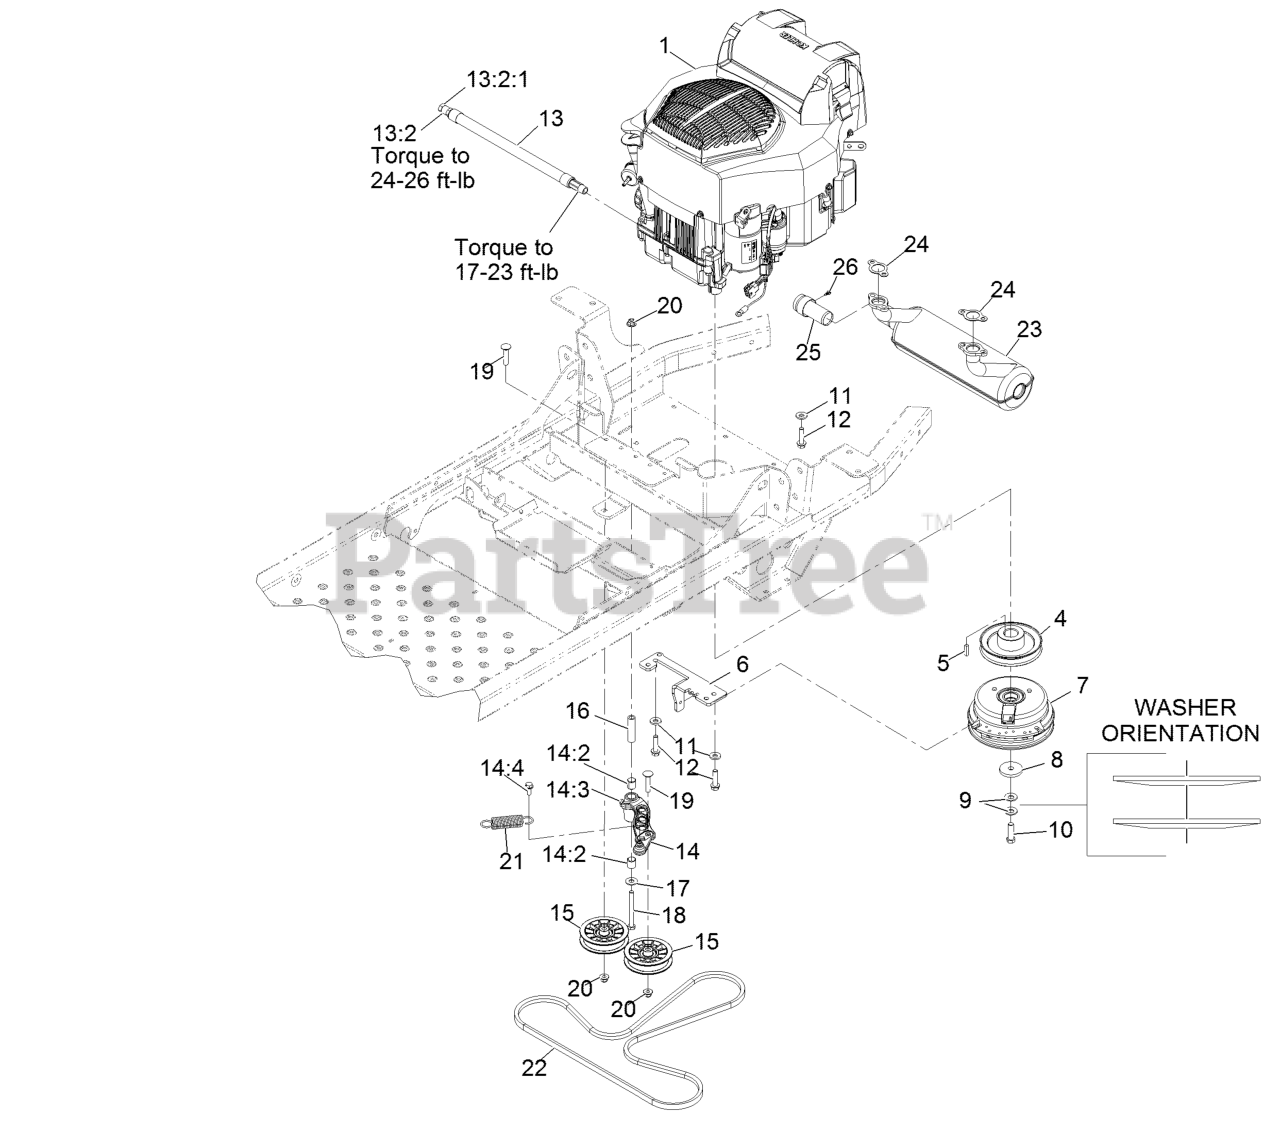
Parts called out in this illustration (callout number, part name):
4	SHEAVE-PUMP, DRIVE
6	ANCHOR-CLUTCH
8	WASHER-CLUTCH
9	WASHER-SPRING
10	SCREW-HH 7/16-20 X 1 1/2 W/LOCTITE
11	WASHER-BELLEVILLE
12	SCREW-HWH
13	OIL DRAIN HOSE ASM
13:2	PLUG-HH
13:2:1	O-RING
14	IDLER ARM ASM
14:2	SLEEVE-BEARING
14:3	FITTING-GREASE, 90 DEG
14:4	SCREW-THD ROLL, HWH
15	PULLEY-FLAT IDLER
16	BUSHING-PIVOT, IDLER
17	WASHER-FLAT
18	SCREW-CARR
19	SCREW-CARR
20	NUT-HF, NI
21	SPRING-EXTENSION
22	V-BELT
23	MUFFLER, KOHLER
24	GASKET-EXHAUST
25	ARRESTOR-SPARK
26	SCREW-HWH
